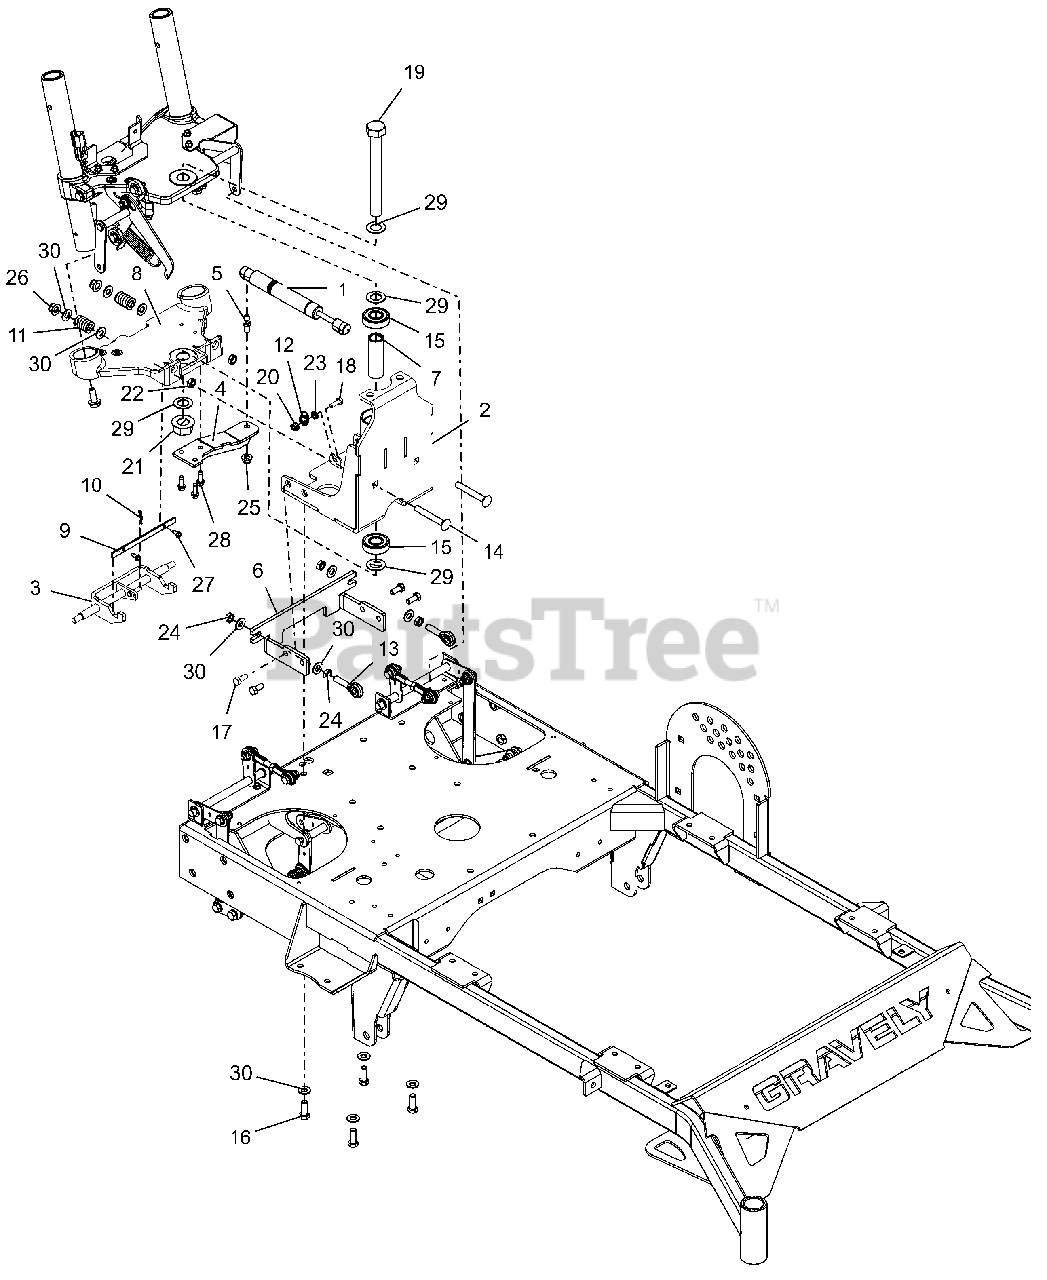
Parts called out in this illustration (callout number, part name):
1	DAMPER, CONTROL
2	WLDMT, BRKT STEERING MTG (RED)
3	WLDMT, STEERING LOCK
4	WLDMT, DAMPENER MTG BRKT (RED)
5	STUD- BALL
6	BRKT, STEERING LOCK MTG (RED)
7	SPCR, STEERING
8	BRKT, LOWER STEERING
9	STRIP, WEAR
10	PIN-HAIR, ENDRIES #25 YWZC
11	SPRG, COMPRESSION
12	SPRG, EXTENSION
13	ROD, END 3/8 RH
14	@BLT-RDHDSQNK .38-16X2.75 G5YZ
15	BRG-BALL .750X1.750X.50
16	@BLT-HEX .38-16X1.00 GR5 YWZC
17	@BLT-HEX .31-18X.75 GR5 YWZC
18	@BLT-HEX .25-20X.75 GR5 YWZC
19	BLT, HEX 0.75-10X6.5 GR5 ZC120
20	NUT-LK-CTR-FLG .25-20 YWZC
21	NUT-HEX-FLG-TPLK .75-10 YWZC
22	NUT-HEX-JAM .375-16 YWZC
23	NUT-LK-CTR JAM .25-20 YWZC
24	NUT-JAM .375-24 YWZC
25	@NUT-LK-NYL-FLG .31-18 YWZC
26	@NUT-LK-NYL-FLG .38-16 YWZC
27	@SCR-TAP 10-24X.50 HWH TR YWZC
28	SCR-TAP-PM .25-20X.75 TR YWZ
29	WSHR-FL-STL .750X1.250X.048 YZ
30	@WSHR-FL-STL.406X.812X.065 YWZ
